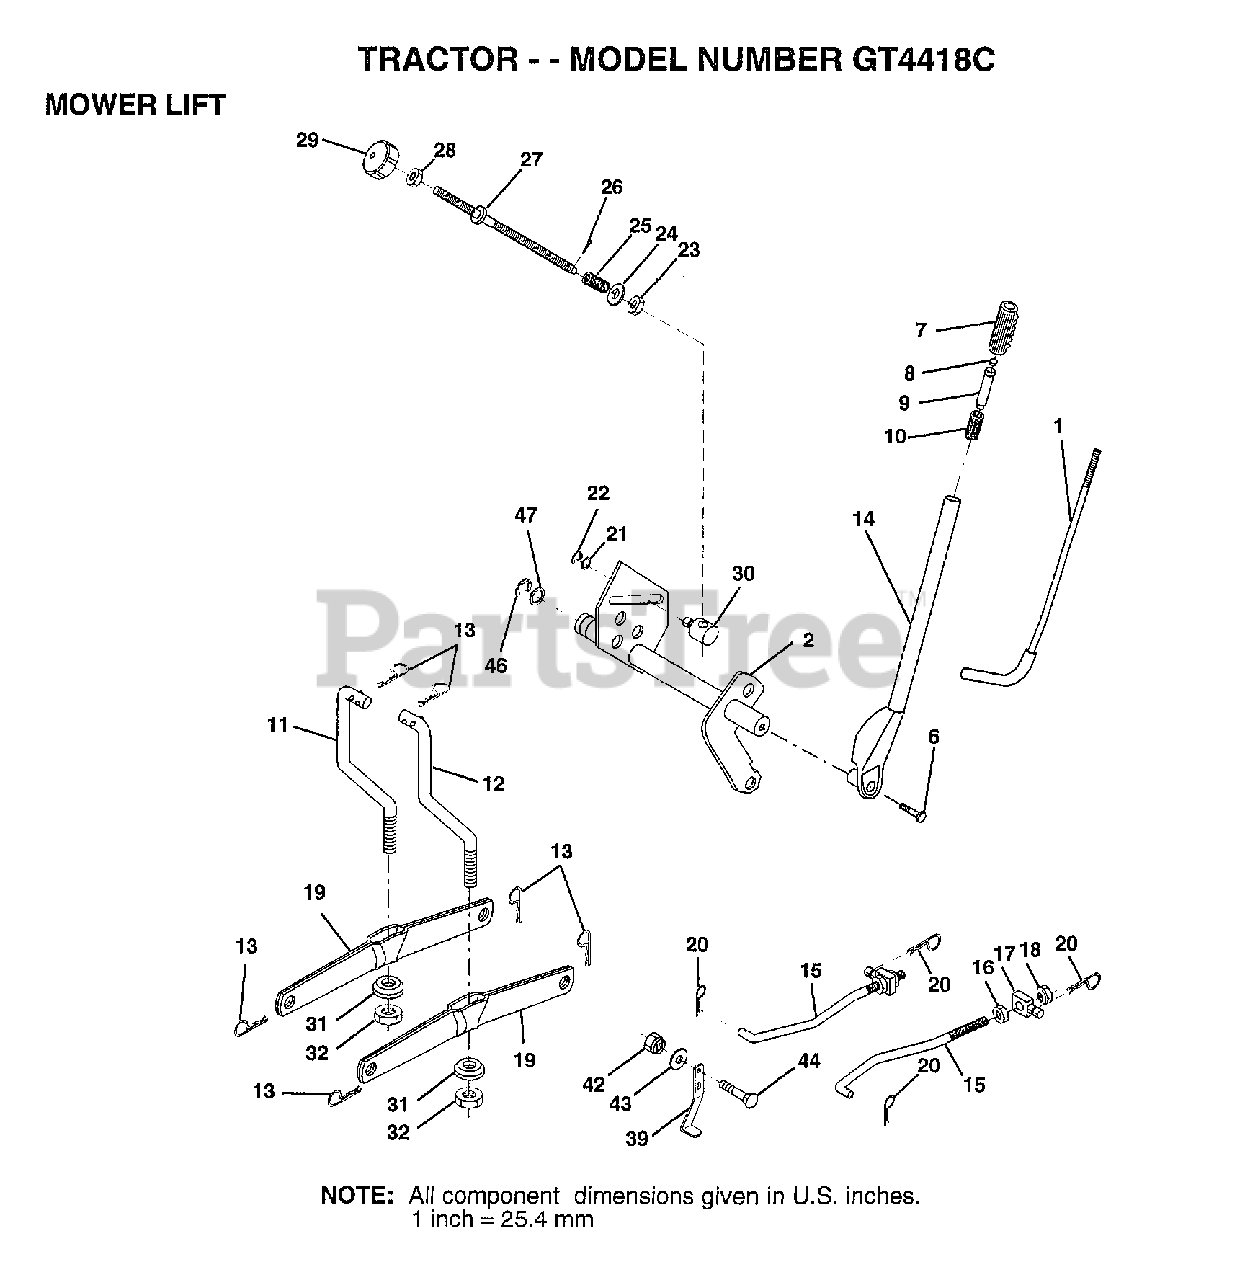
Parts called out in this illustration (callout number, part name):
1	LEVER ROD LT
2	SHAFT LIFT W/IND
6	"BOLT,HEX"
7	GRIP
10	SPRING T
11	LINK.LIFT.LH.GTV
12	LINK.LIFT.RH.GTV.
15	LINK.FRONT
16	NUT
17	TRUNION
18	NUT.LK.W/WSH.1/2.
19	ARM SUSP REAR
20	RETAINER.SPRING
21	WASHER
22	KLIP RING
23	NUT T
24	WASHER
25	SPRING T
27	ROD.ADJ.LIFT
28	NUT
29	KNOB INF 3/8-16
30	TRUNION LT
31	BEARING PVT LH
32	NUT.LOCK.3/8-24
39	STOP.OVER.CENTER
43	WASHER GT
44	BOLT
46	E-RING
47	WASHER
